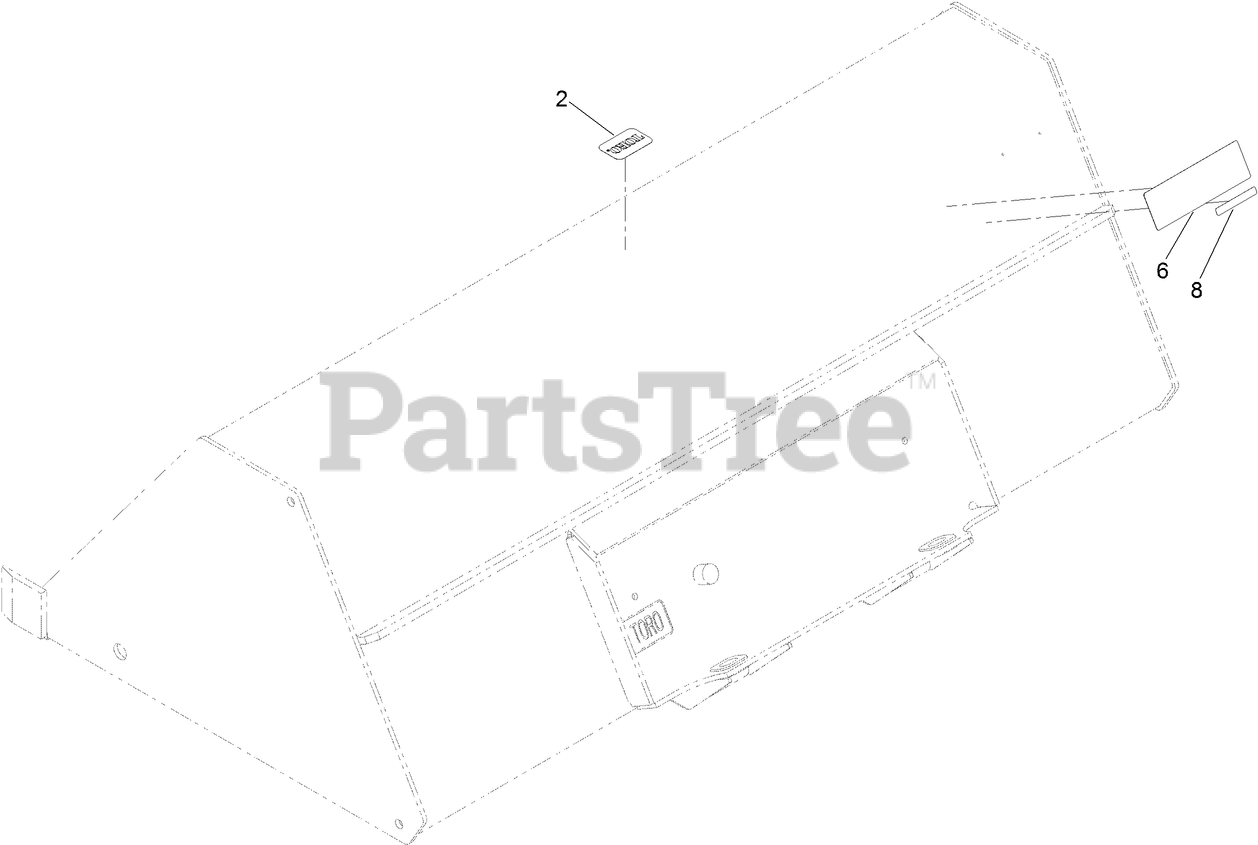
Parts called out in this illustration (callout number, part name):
2	DECAL
6	DECAL-CAPACITY
8	DECAL-WARNING
